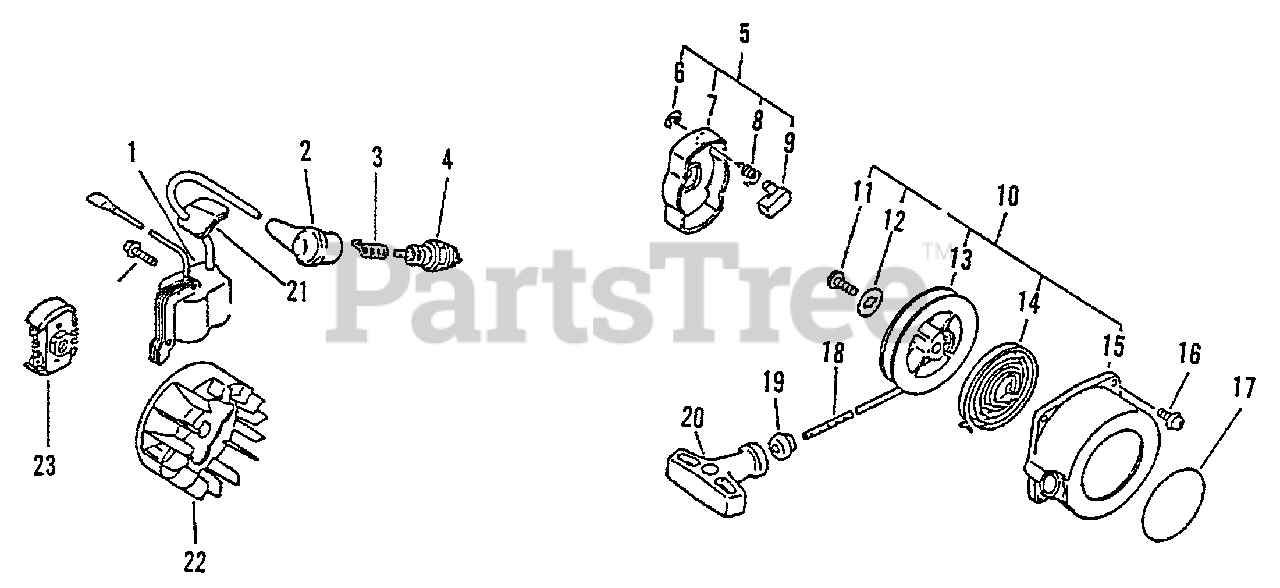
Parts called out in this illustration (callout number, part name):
1	COIL, IGNITION
2	CAP, SPARK PLUG
3	TERMINAL, SPARK PLUG CAP
4	SPARK PLUG -- BPM-7Y
5	STARTER PAWL ASSY
6	CATCHER, PAWL
7	RING, RETAINING - 4
8	SPRING, RETURN
9	PAWL, STARTER
10	STARTER ASSY
12	WASHER
13	REEL, ROPE
14	SPRING, REWIND
15	CASE, STARTER
16	SCREW - 4X16
17	LABEL - ECHO
18	ROPE, STARTER - 3X890
19	GUIDE, ROPE
20	GRIP, STARTER
21	GROMMET
22	FLYWHEEL
23	CLUTCH ASSY
24	SCREW - 4X22
